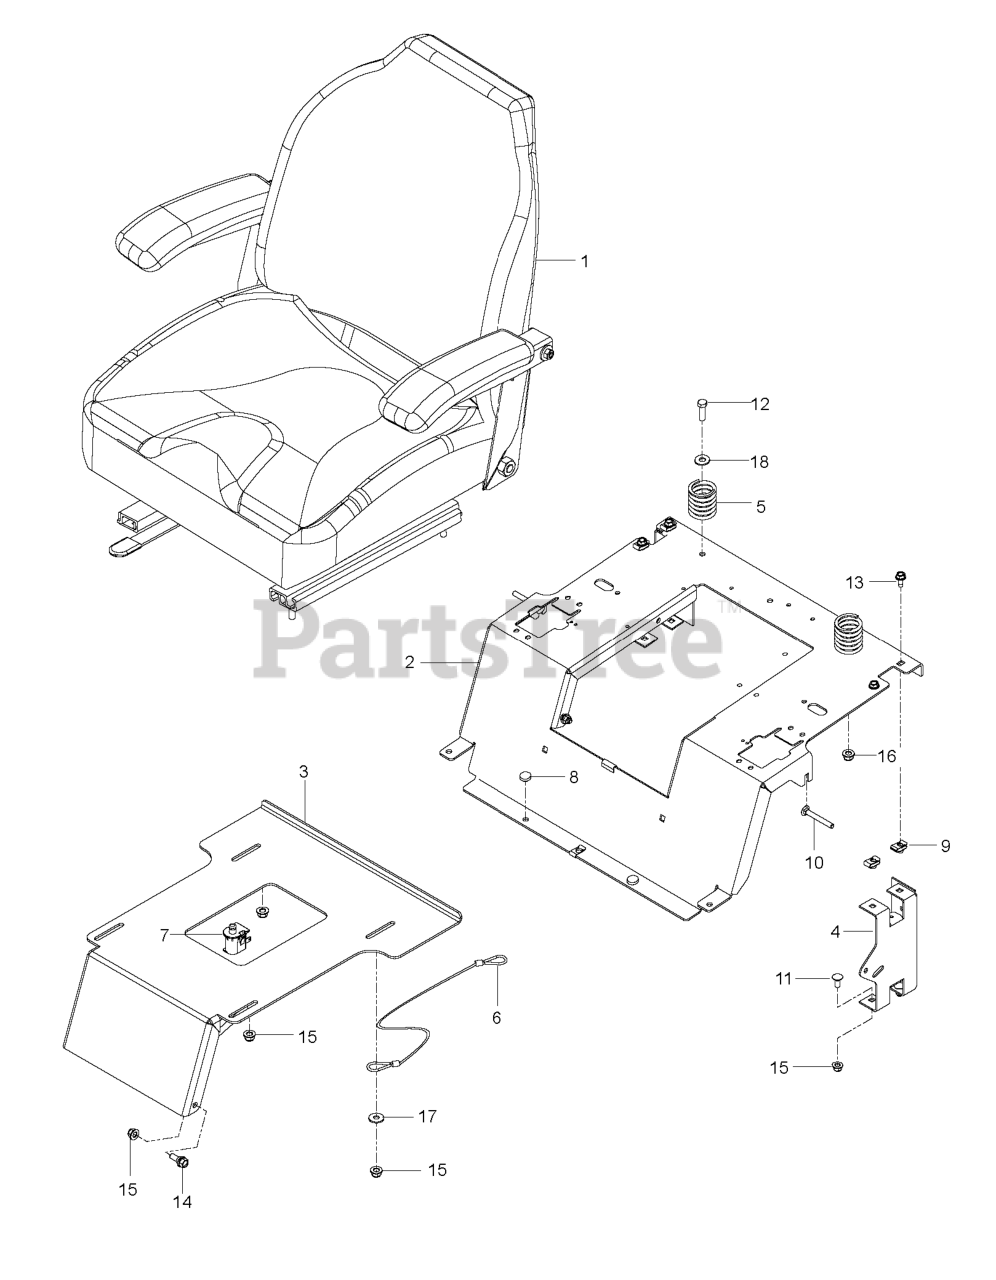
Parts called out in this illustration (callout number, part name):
1	SEAT.907.VINYL.HUSQVARNA
2	SUPPORT SEAT FLAT ORANGE
3	PAN, SEAT ORG
4	SUPPORT REAR SEAT BLACK
5	SPRING.COMPRESSION.SEAT.BLACK
6	SEAT LANYARD
7	SEAT SWITCH
8	GROMMET, BUMPER
9	U-CLIP 5/16-18 NUT RETAINER
10	RHSNB 5/16-18 X 2-1/2 GR5 ZD
11	RP BOLT 5/16-18 X3/4 ZN/YEL GR
12	HCS 3/8C X 1 1/4 GR5
13	SCREW.THDROL.5/16-18X3/4.TTY
14	SB 5/16-18 HEX HD GD5, BLK ZN
15	5/16-18 NYLOC FLANGE NUT
16	NUT 3/8-16 HEX FLG NYLOC ZD
17	WASHER.5/16.FLAT.STE.STD.
18	RP WASHER 3/8 FLAT
